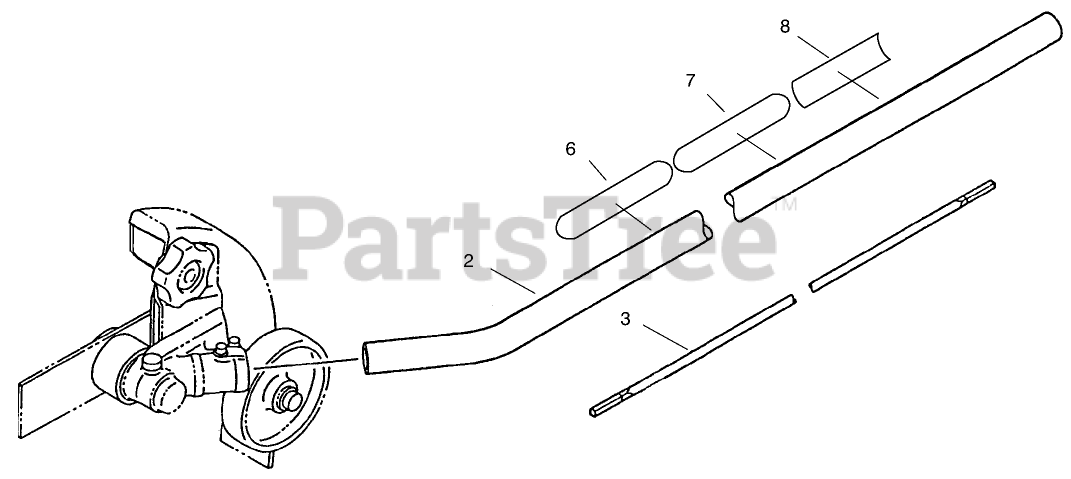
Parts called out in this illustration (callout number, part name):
2	TUBE - DRIVESHAFT
3	DRIVESHAFT
6	DECAL - CAUTION
7	DECAL - CAUTION
8	DECAL - TORO
